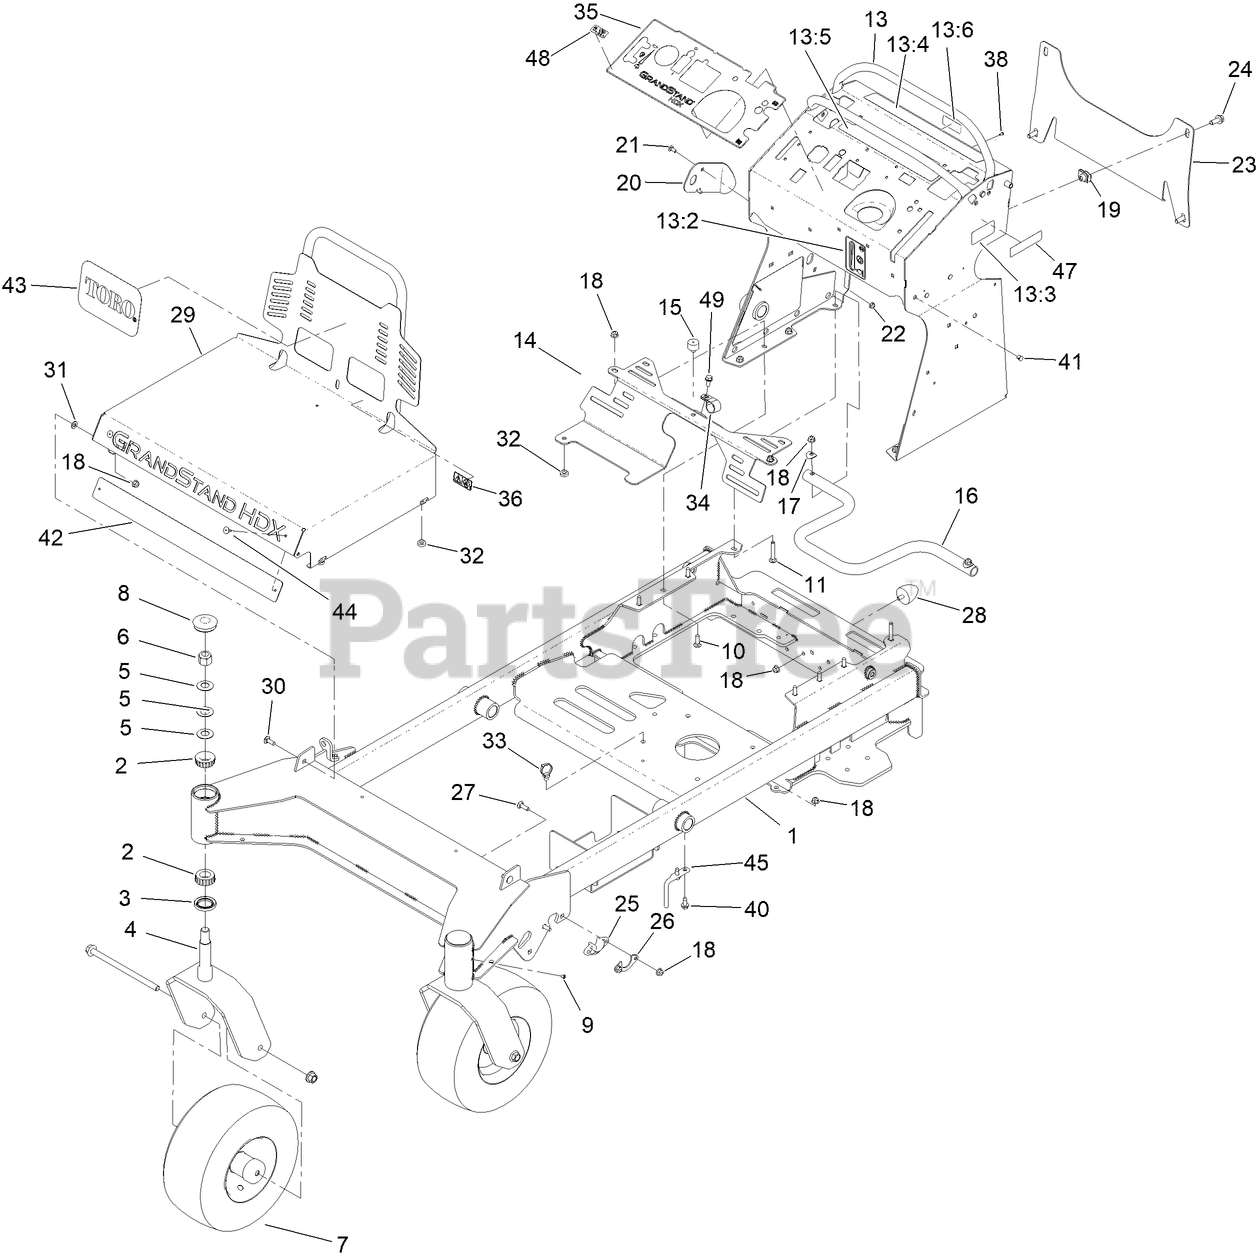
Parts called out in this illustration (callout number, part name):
1	FRAME-60 [RED]
2	BEARING-ROLLER, TAPERED
3	SEAL-GREASE
4	CASTER-FORK [RED]
5	WASHER-BELLVILLE
6	NUT-LOCK, NI
7	ASM-WHEEL BRGS AXLE 13X6.50-6
8	CAP,GREASE
10	BOLT-CARR
11	BOLT-CARR
13	TOWER DECAL ASM
13:2	DECAL-OIL LEVEL
13:3	DECAL-FILL, FUEL
13:4	DECAL-WARNING
13:5	DECAL-CONTROLS
13:6	DECAL - FUSE
14	GUARD-FAN
15	BUMPER-GROMMET
16	TUBE-FUEL TANK MOUNT
17	WASHER
18	NUT-HF, NI
19	NUT-TINNERMAN
20	PLATE-STRIKER
21	SCREW-CARR
22	NUT-HF
23	BRACKET-CROSS
24	SCREW-HHF
25	BEARING-FLANGE
26	GUSSET-LIFT, DECK
27	SCREW-CARR
28	BUMPER-RUBBER
29	ASM-ENGINE GUARD [SERVICE]
30	BOLT-CARR
31	SPACER-NYLON
32	BUMPER
33	CLIP-TIE
34	CLAMP-R
35	DECAL-PANEL CONTROL, KAWASAKI
36	DECAL-WARNING, NO RIDERS
38	RIVET-POP
40	SCREW-HWHTF
41	DOME PANEL PLUG
42	PLATE-BACKING
44	RIVET-POP
45	GUIDE-BELT
47	DECAL-SPARK ARRESTER
48	DECAL-SHUTDOWN, CE
49	SCREW-HWHTF
